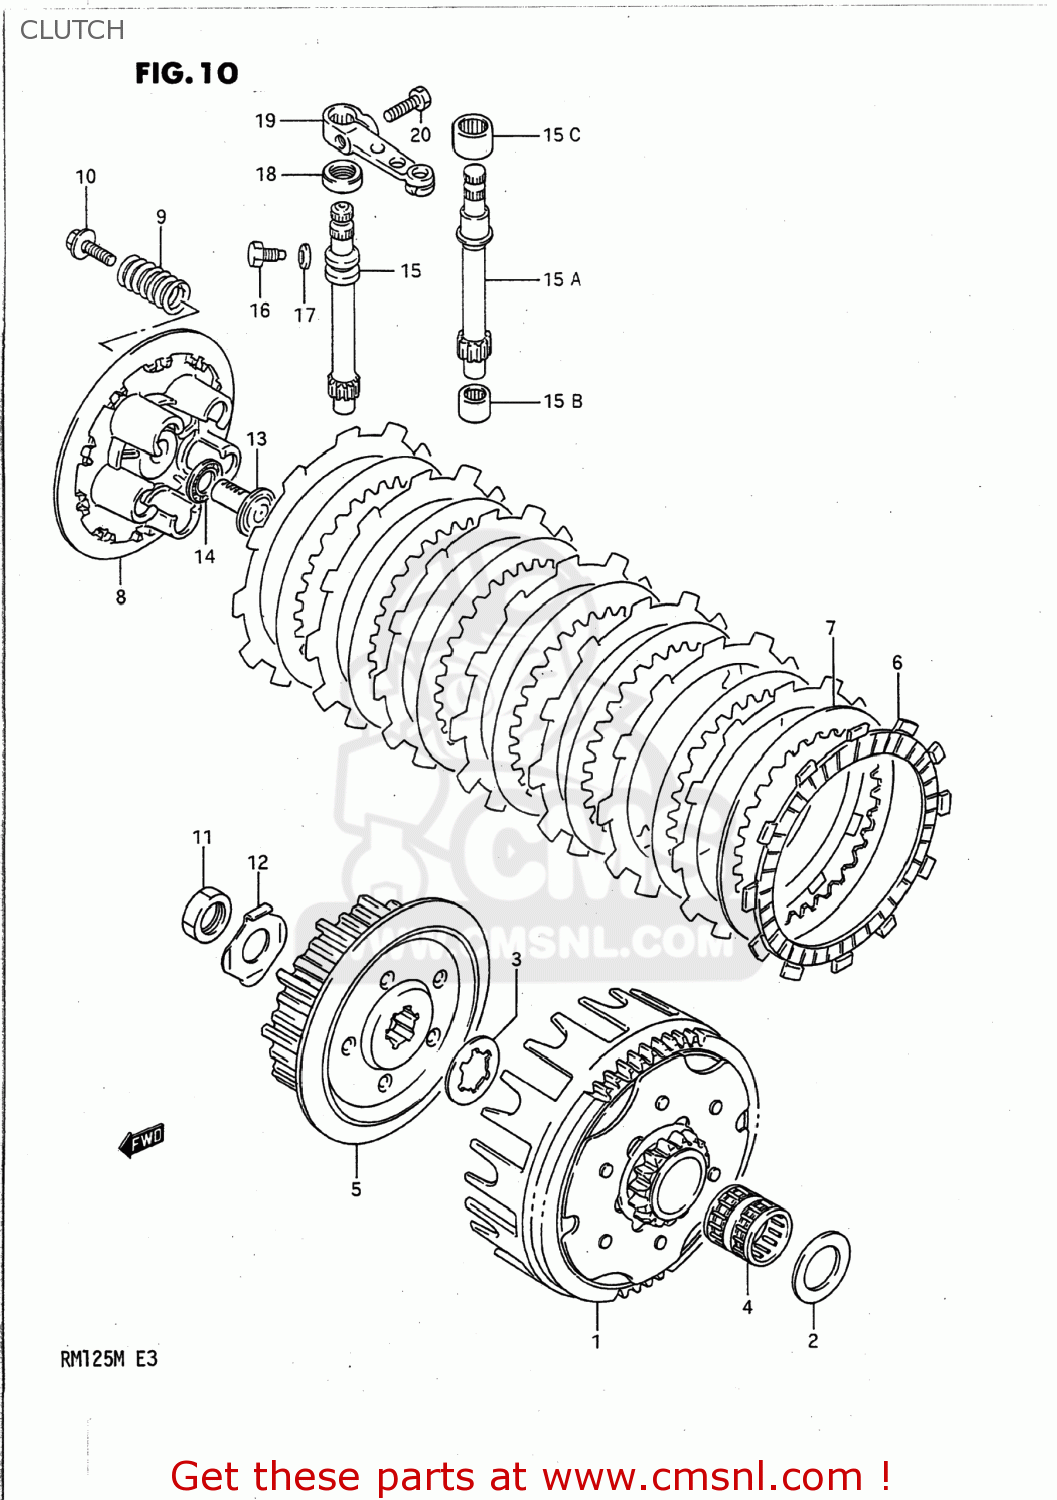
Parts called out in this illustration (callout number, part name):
1	GEAR ASSEMBLY,PRIMARY DRIVE
2	WASHER,THRUST
3	WASHER,LOCK
4	BEARING(20X25X26)
5	HUB,CLUTCH SLEEVE
6	PLATE,CLUTCH DRIVE (MCA)
7	PLATE,DRIVEN(T:1.4)
8	DISC,CLUTCH PRESSURE
9	SPRING
10	BOLT 5X16
11	NUT
12	WASHER
13	RACK,CLUTCH RELEASE
14	BEARING(10X22X2.8)
15	PINION,CLUTCH RELEASE
15A	PINION,CLUTCH RELEASE
15B	BEARING(9X13X10)
15C	BEARING(12X16X10)
16	BOLT
17	GASKET(6.2X11X1).2 (NAS)
18	SEAL,OIL(10X17X5)
19	ARM,CLUTCH RELEASE
20	BOLT
